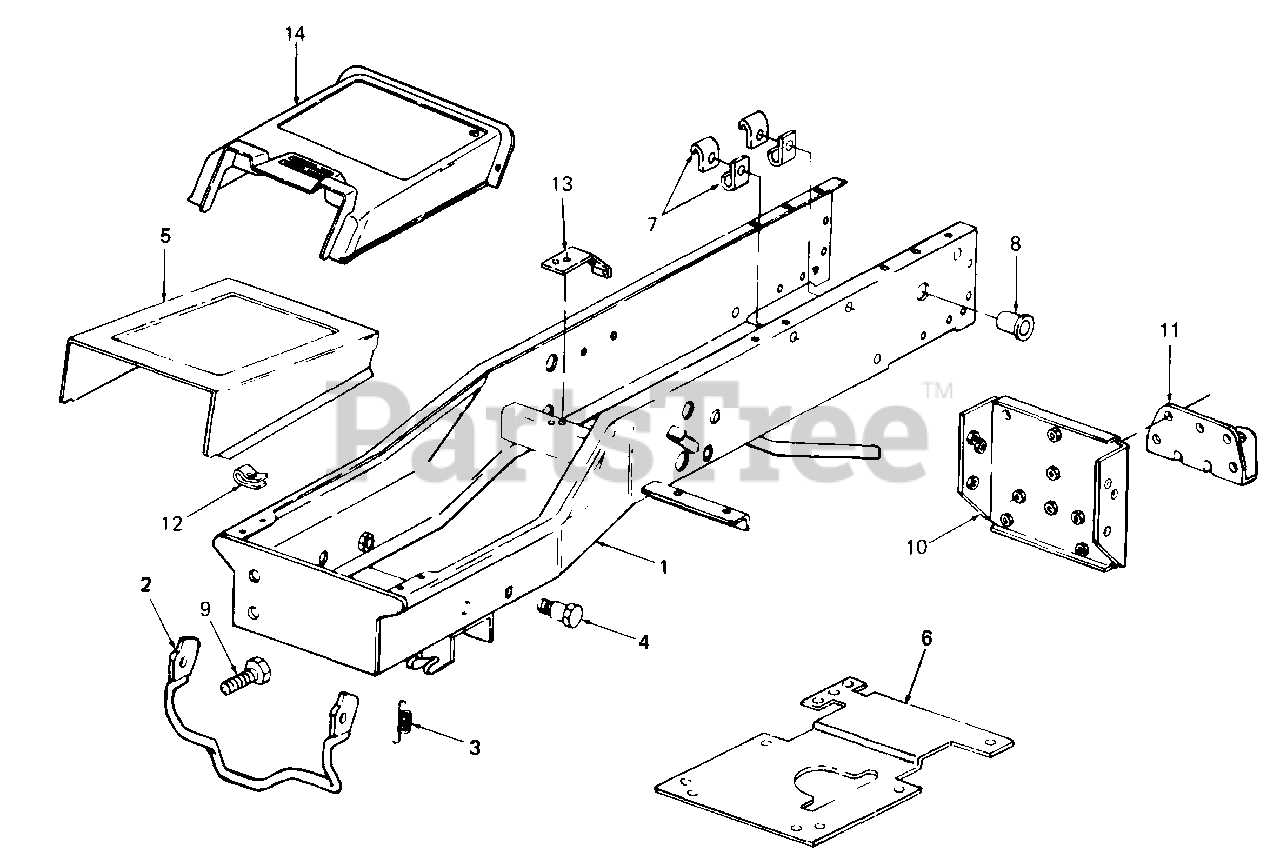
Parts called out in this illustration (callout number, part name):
3	Spring, Latch
4	Bolt, Shoulder
5	Cover, Frame w/Graphic
7	Clip, Cable
8	Bushing, Snap
9	Screw, Adjustment, 1/2-20 X 1.0 Lg GR5
12	Nut, Speed
13	Bracket, Switch
14	Cover, Frame
